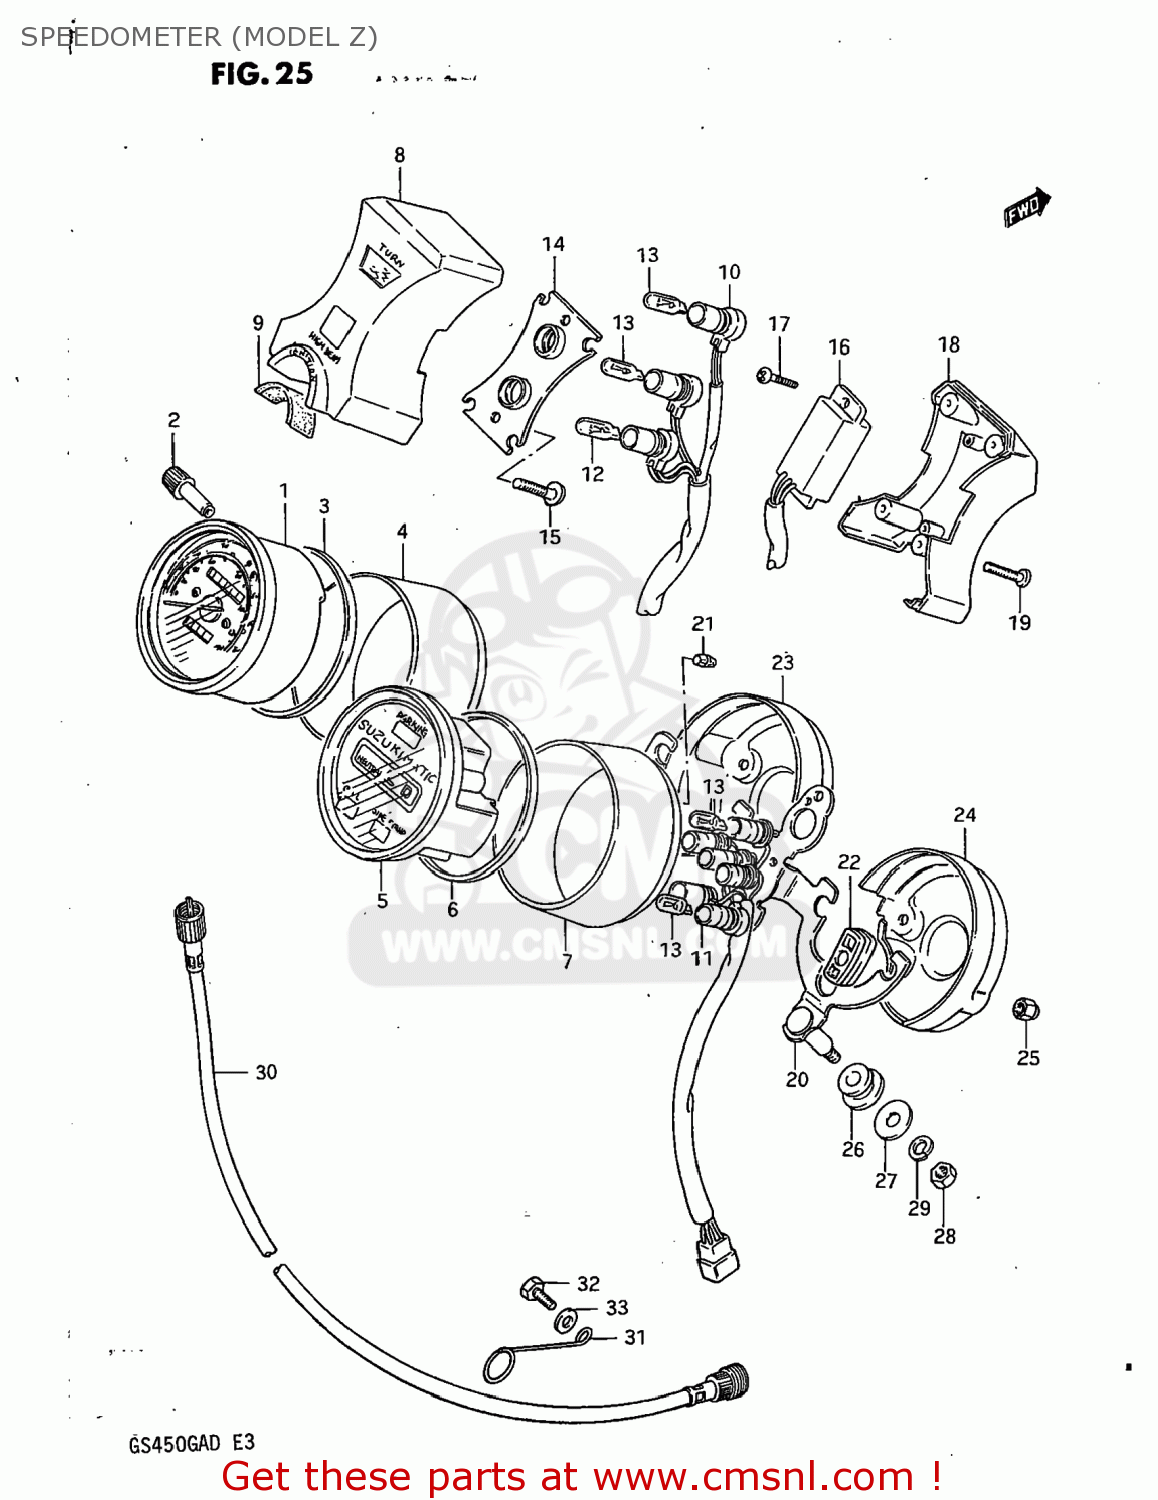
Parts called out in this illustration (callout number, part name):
1	SPEEDOMETER ASSEMBLY
2	KNOB
3	CUSHION
4	COVER,SPEEDOMETER
5	INDICATOR ASSEMBLY,GEAR POSITION
6	CUSHION
7	COVER,TACHOMETER
8	CASE,PILOT BULB
9	SEAL,IGNITION SWITCH
10	SOCKET
11	SOCKET,GEAR INDICATOR
12	BULB(12V1.7W,T10,WB121)
13	BULB(12V3.4W,T10)
15	SCREW
16	WARNING LAMP,SIDE STAND
17	SCREW,GEAR INDICATOR
18	COVER,PILOT BOX,UNDER
19	SCREW,INDICATOR
20	BRACKET,COMBINATION METER
21	CUSHION
22	CUSHION,METER
23	ORNAMENT,SPEEDOMETER
24	COVER,INDICATOR,UNDER
25	NUT
26	CUSHION,METER BRACKET
27	WASHER (8.5X29X1.6)
28	NUT
29	LOCK WASHER
30	CABLE ASSY,SPEEDOMETER
31	CLAMP,SPEEDOMETER CABLE
32	BOLT, UPPER
33	WASHER
